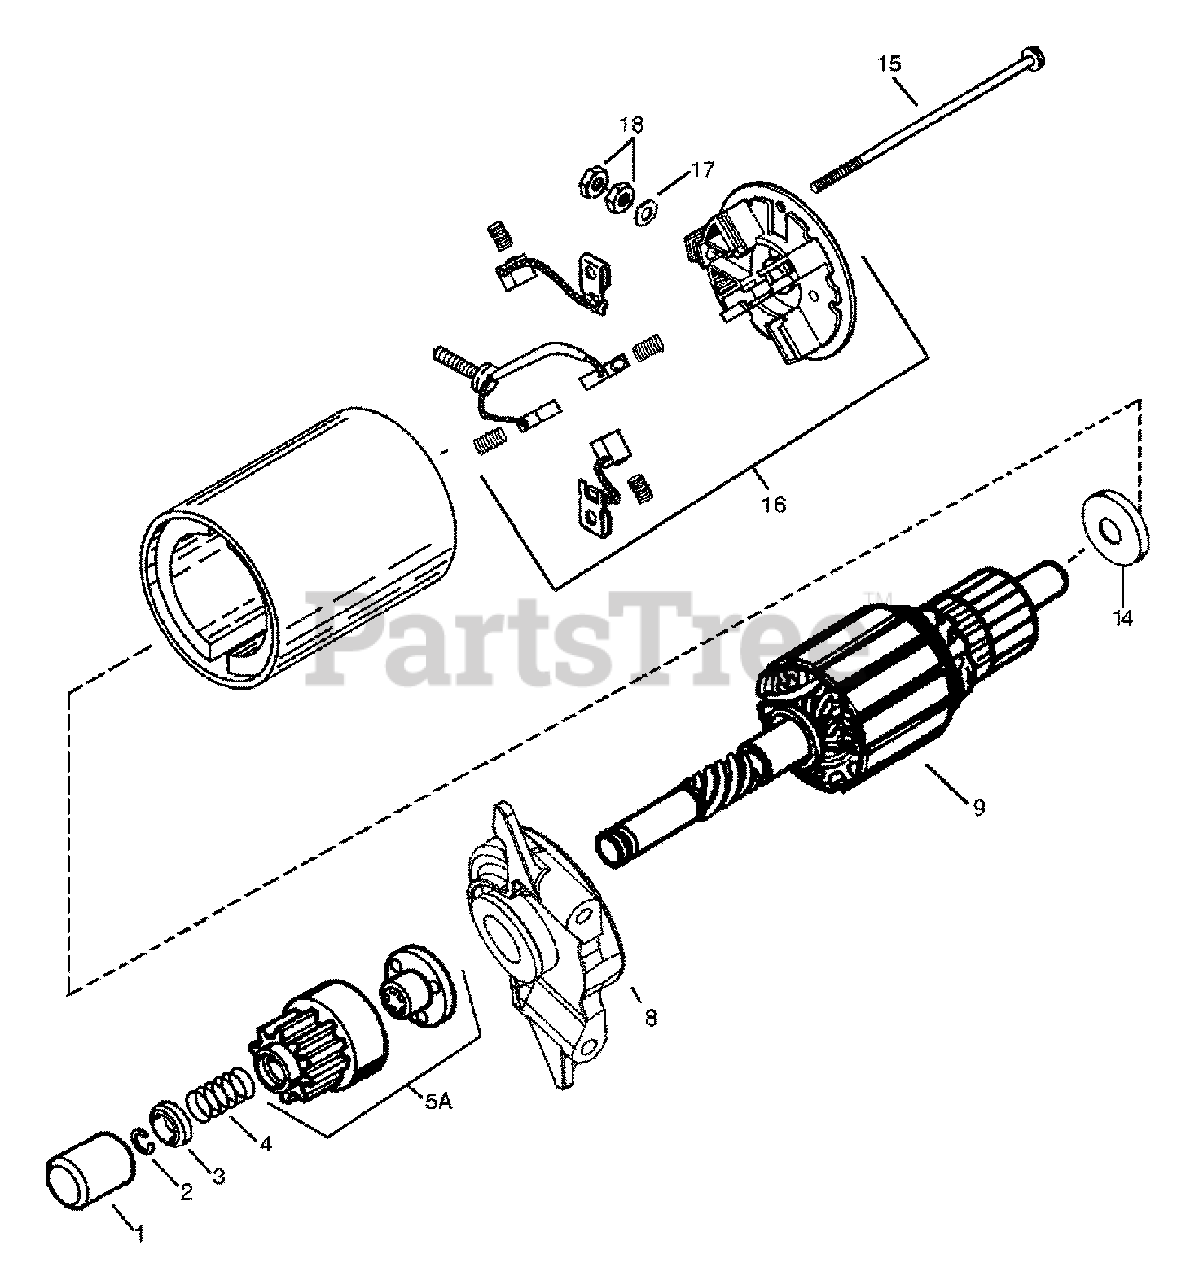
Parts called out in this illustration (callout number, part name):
2	Retainer Ring
3	Spring Retainer
4	Anti-drift Spring
5A	Gear & Nut
8	Drive End Cap Assembly
14	Thrust Washer
16	End Cap & Brush Card Ass'y
17	Washer
